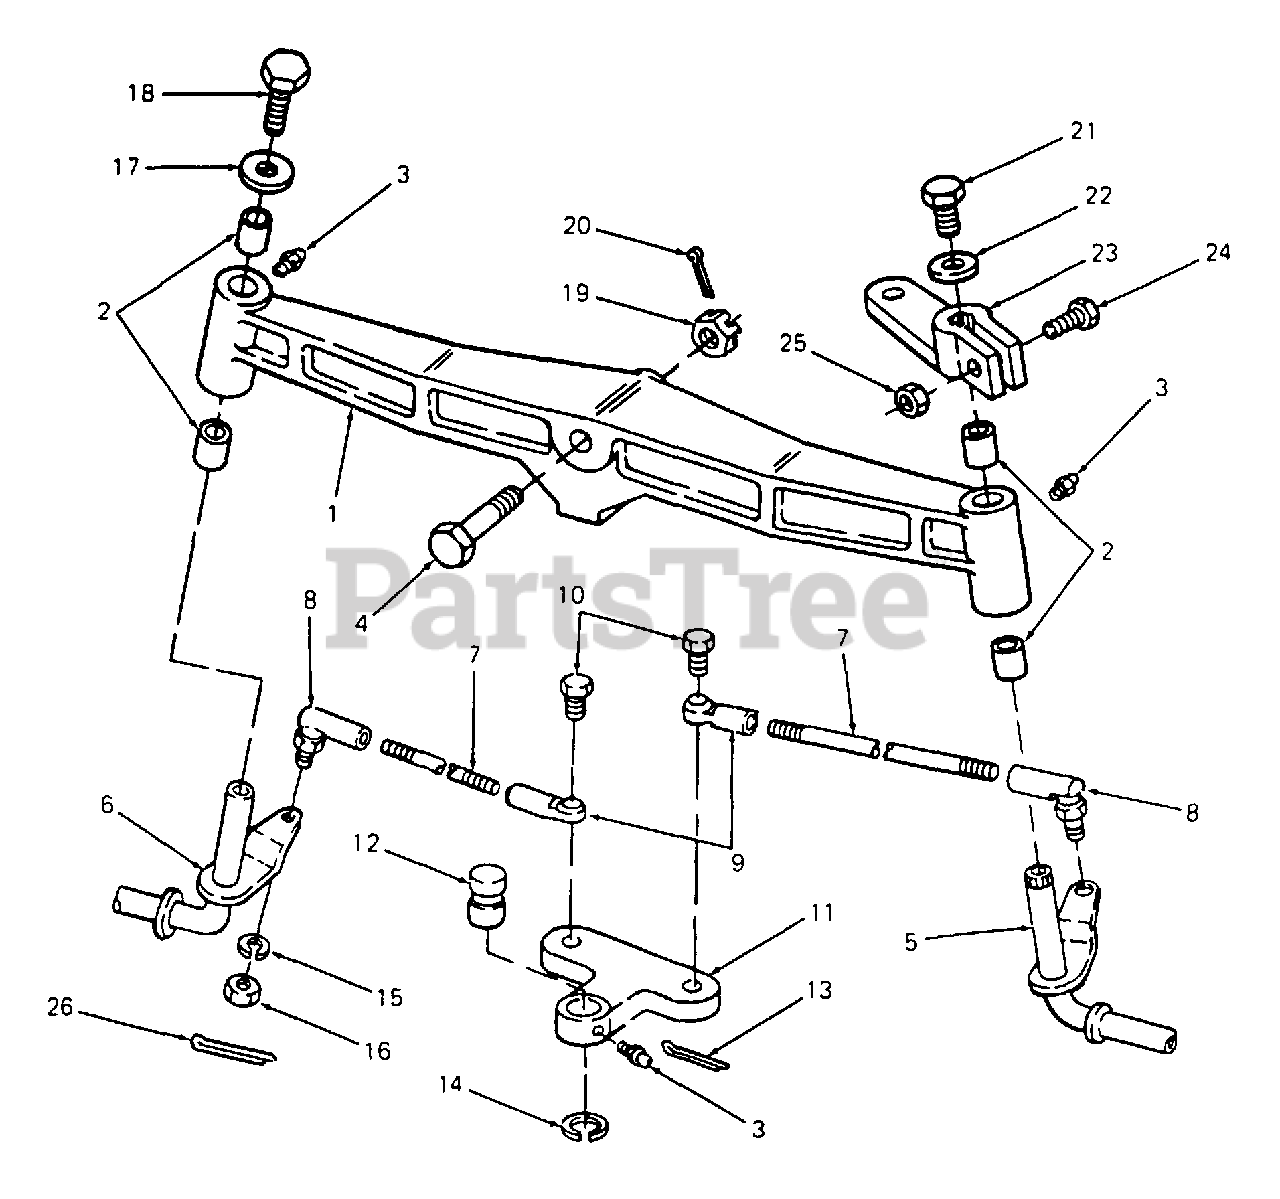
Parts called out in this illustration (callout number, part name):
1	Axle Assy, Front
3	Fitting, Lube, 3/16 Drive
4	Bolt, Hex, 3/4-10 x 5.0 Lg GR5 w/Hole 1
8	Ball Joint, 1/2-20
9	Alignabal End
10	Screw, Hex Cap, 3/8-16 x 1.5 Lg GR5 w/Hole
11	Steering Lever w/Fitting
12	Pin, Steering Pivot
13	Pin, Cotter, 3/32 Dia x 1.0 Lg
14	Ring, Retaining
15	Washer, Lock, 1/2 Dia
16	Nut, Hex Castle, 1/2-20 GR5
17	Washer, Flat, .531 x 1.75 x .090 Thk
18	Screw, Hex Cap, 1/2-13 x 75 Lg GR5
19	Nut, Hex Castle, 3/4-10
20	Pin, Cotter, 1/8 x 1.5 Lg
21	Screw, Hex Cap, 3/8-24 x 1.00 Lg GR5
22	Washer, Flat, .406 x 1.5 x .112 Thk
23	Arm, Steering
24	Screw, Hex Cap, 5/16-18 x 1.38 Lg GR5
25	Nut, Hex Center Lock, 5/16-18 GR5
26	Pin, Cotter, 3/32 Dia x 1.25 Lg
